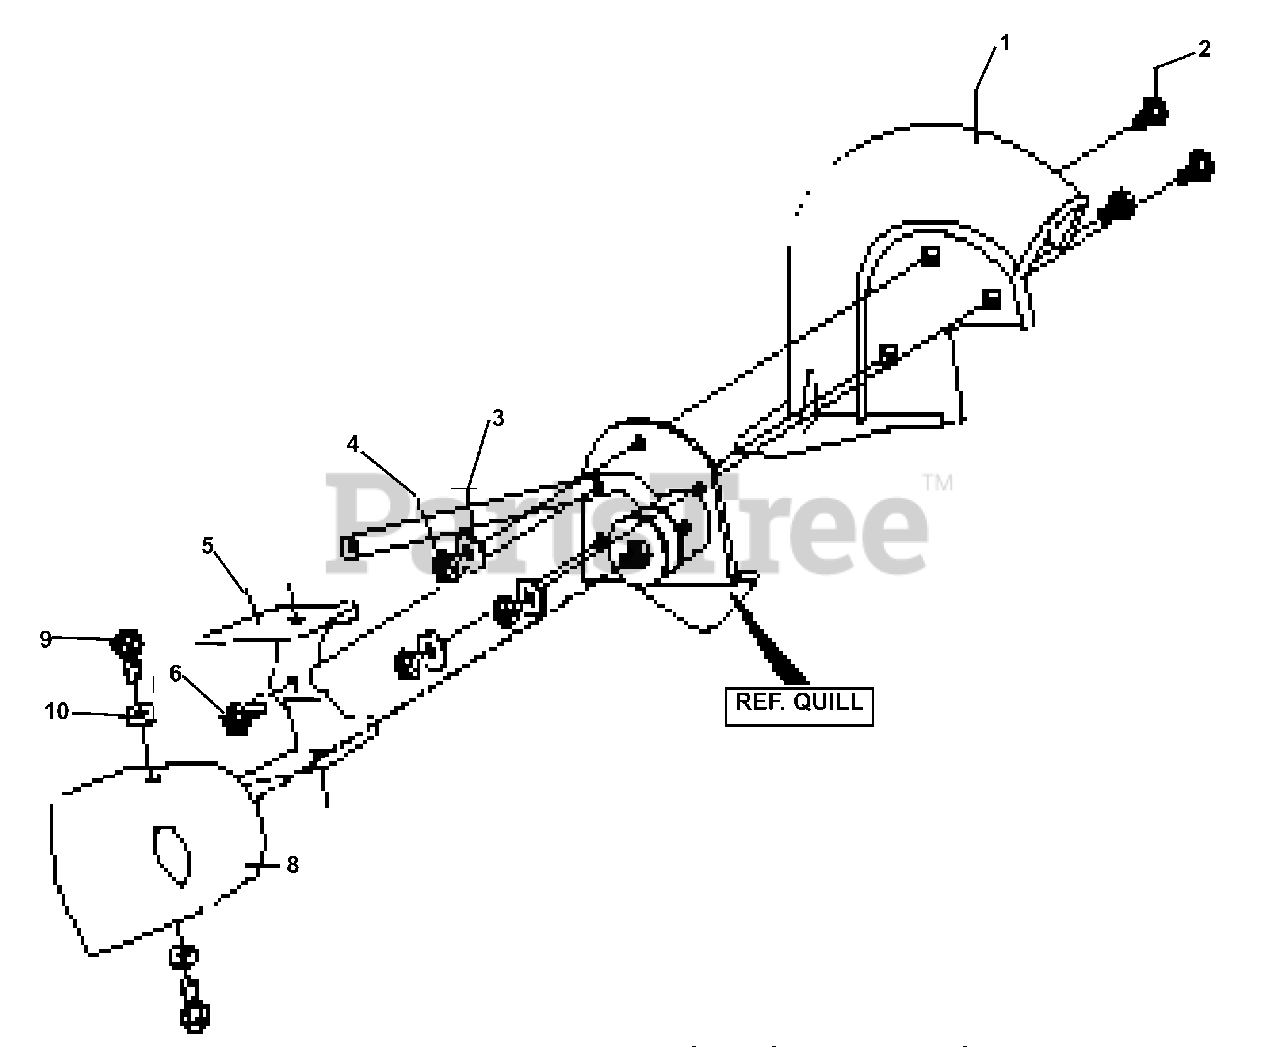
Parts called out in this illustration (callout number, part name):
1	Blade Guard
2	Carr. Bolt 5/16-18x.63
3	Flatwasher .344x.69x.065
4	Nut, 5/16-18 Reghexctrlk
5	Guide, Belt Front
6	Screw, 1/4-20x.50 Tap
8	Cover, Quill Pulley
9	Screw, 10-24x.50 Tap
10	Flatwasher .203x.56x.040
